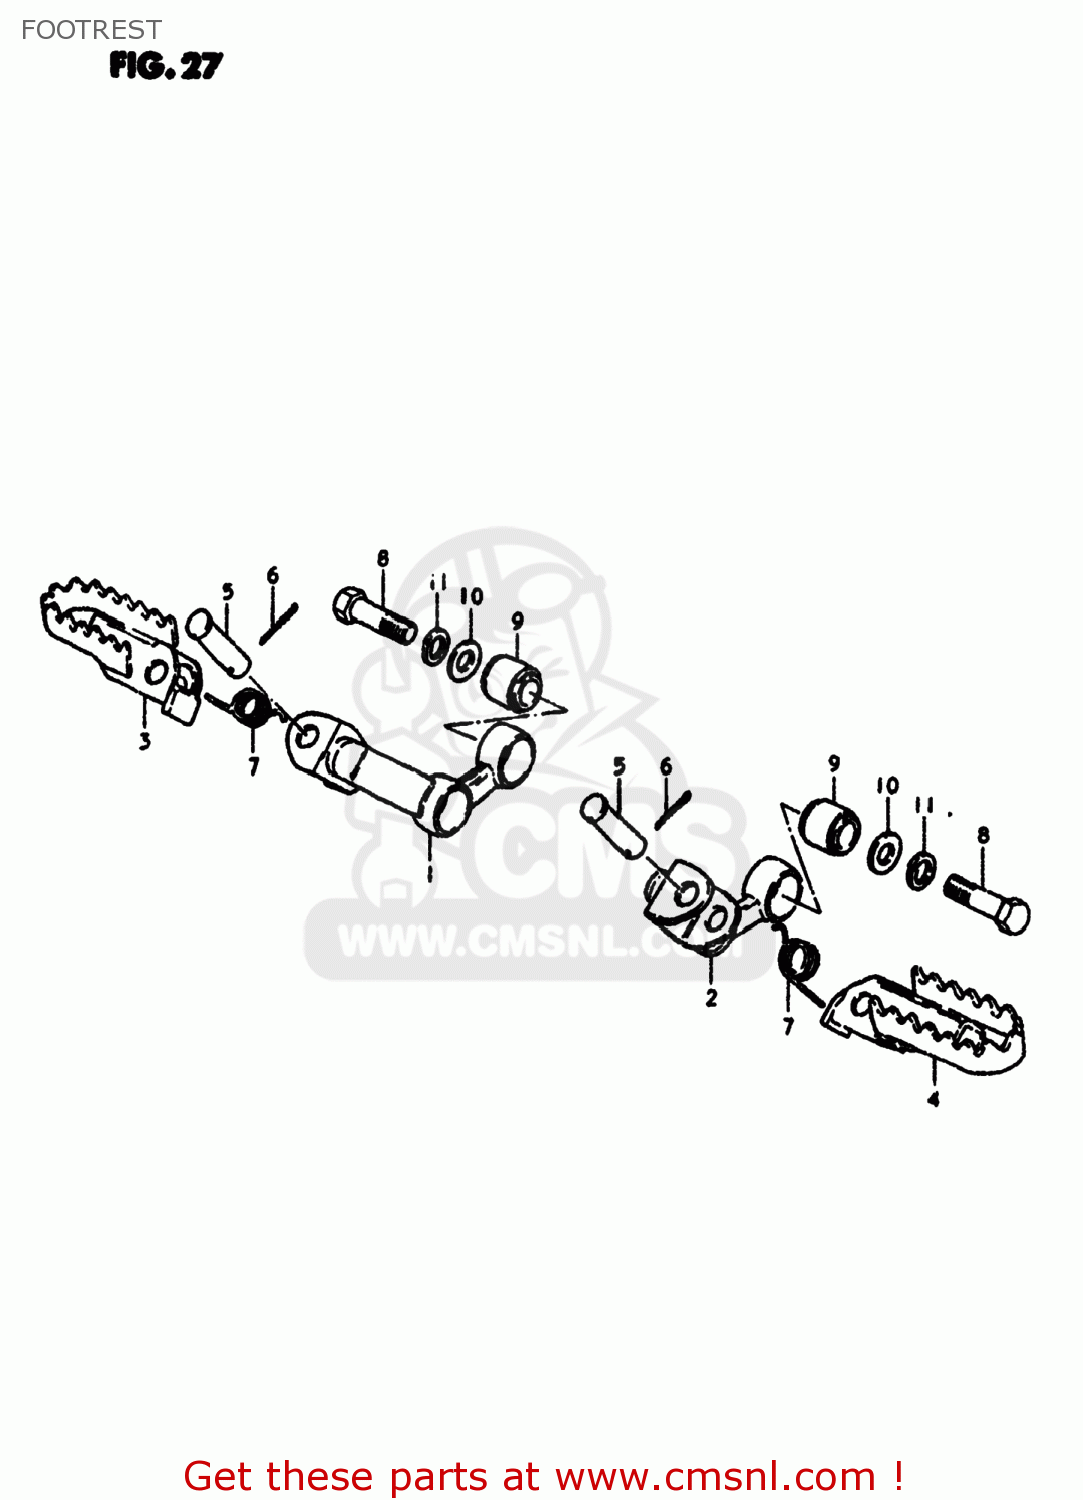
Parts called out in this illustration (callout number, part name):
1	BAR,FRONT FOOTREST
2	BRACKET COMP,FRONT FOOTREST
3	FOOTREST,FR,R
4	FOOTREST,FR,L
5	PIN
6	PIN 20X20
7	SPRING
8	BOLT
9	BUSH
10	WASHER (10.1X21X2.3)
11	LOCK WASHER
